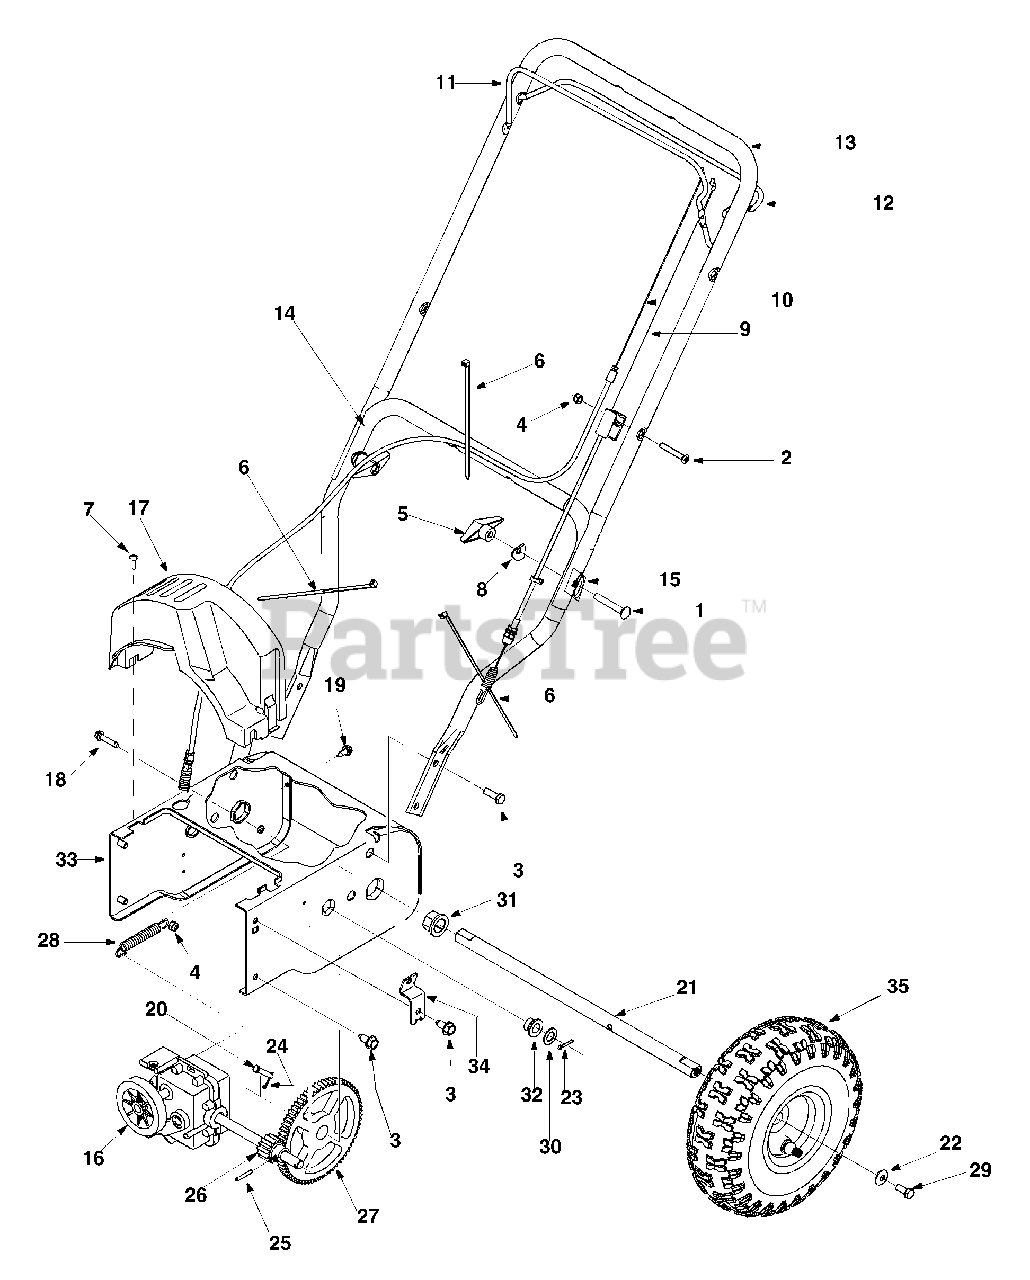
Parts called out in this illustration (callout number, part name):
1	Carriage Screw 5/16-18 x 2.25"
2	Mach. Screw 1/4-20 x 1.825"
3	Screw, 5/16-12 x.75"
4	Flange Lock Nut 1/4-20
5	Handle Knob Assembly
6	Cable Tie
7	Hex Screw, #10-16 x.500
8	Saddle Washer
9	Auger Cable
10	Drive Cable
12	Drive Control
15	Handle Tab
16	Transmission Assembly
17	Belt Cover
18	TT Screw 1/4-20 x 1.25"
19	Screw, 1/4-20 x.625"
20	Clevis Pin
21	Axle
22	Bell Washer
23	Cotter Pin, 1/8 x 1.0
24	Cotter Pin, 3/32 x.750
25	Roll Pin
26	Pinion 14T
27	Gear 70T
28	Extension Spring
29	Lock Bolt 5/16-24 x 0.75"
30	Flat Washer
31	Hex Flange Bearing
32	Hex Flange Bearing
